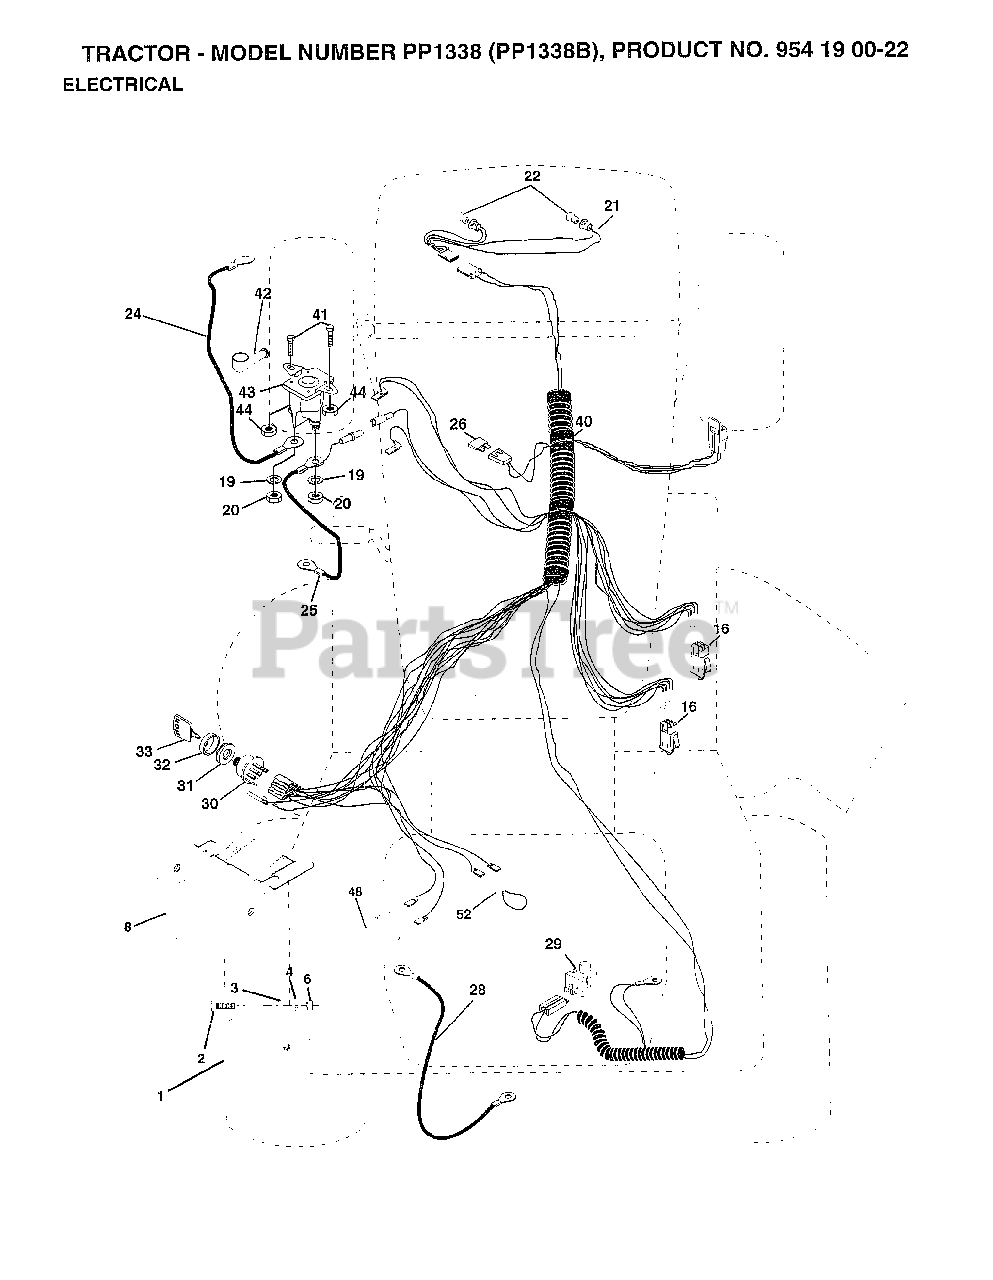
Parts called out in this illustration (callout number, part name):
3	WASHER
4	LOCKWASHER
8	"CASE,BATTERY.MECH"
16	SWITCH INTERLOCK
20	NUT
21	"HARNESS,LIGHT SOC"
22	HEADLAMP BULB
24	CABLE ASM.
25	CABLE.BTRY.6GA.RD
26	FUSE HYT
28	CABLE T
29	SWITCH SEAT
30	SWITCH IGN 4POS
31	NUT IGNITION
32	COVER KEY SWITCH
33	KEY
40	HARNESS-IGNITION
41	BOLT HXHD FIN
44	NUT HXKEP 1/4X20
48	ADAPTER AMMETER
52	PROTECTION LOOP
